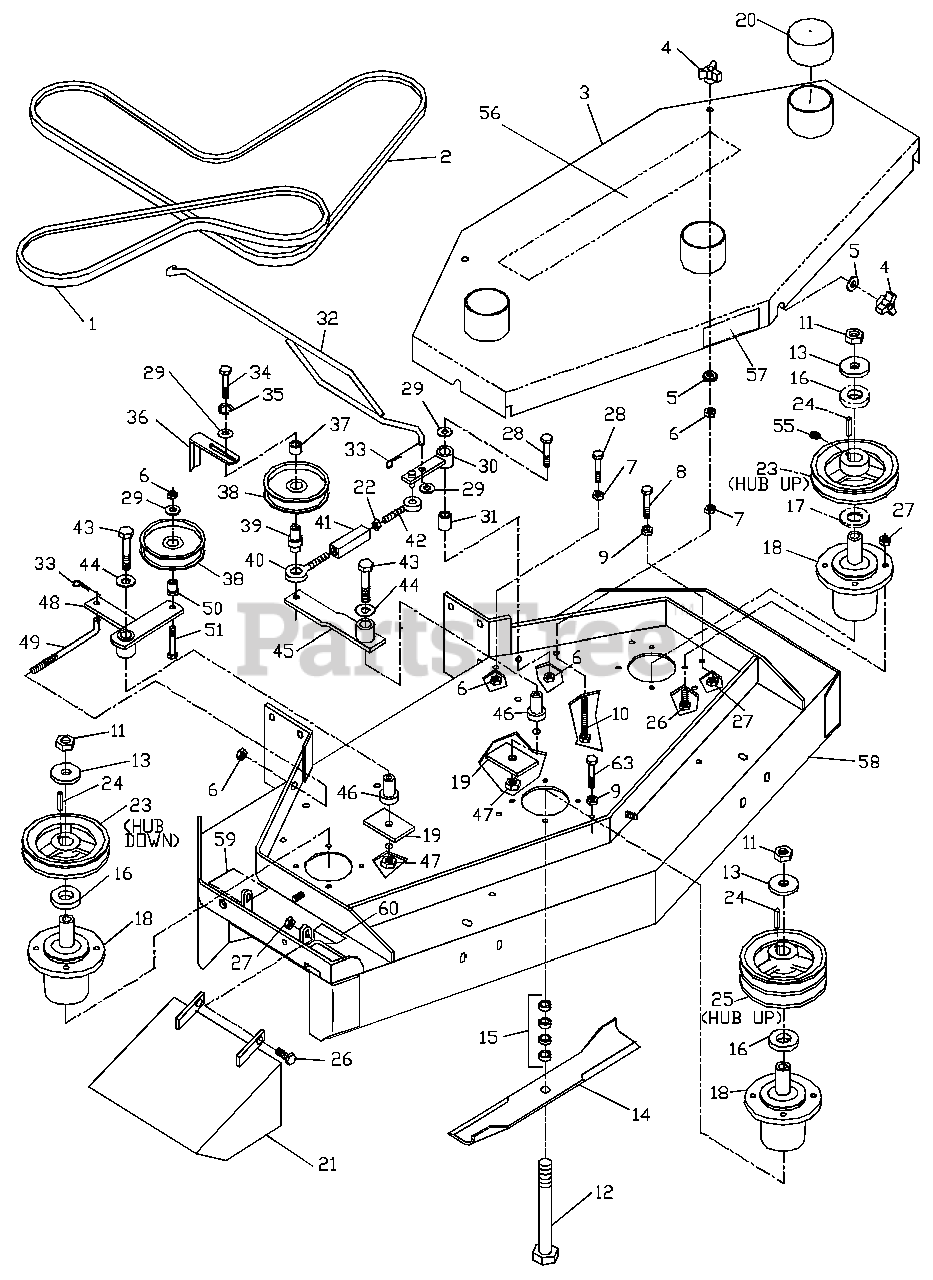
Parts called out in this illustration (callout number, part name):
1	AUX. BLADE BELT
2	BLADE BELT 48
3	48" BELT SHIELD
4	THREE PRONG KNOB
5	3/8 SEALING WASHER
8	HCS 5/16CX3 (BELT GUIDE)
9	HFLN 5/16C
10	TAPBOLT-3/8C X 4 1/2
12	HCS 5/8F X 8 1/2
12	HCS 5/8F X 9 (CENTER)
13	SUPPORT WASHER
14	BLADE 16 1/4"
15	BLADE SPACERS
17	MACH. BUSHING 10 GA.
18	HOUSING ASM.
21	DEFLECTOR CHUTE
22	5/16C HEX NUT
23	PULLEY W/SETSCREWS
24	1/4SQ. KEY X 1 1/8
25	DOUBLE PULLEY W/SETS.
26	HCS 5/16C X 1
28	HCS 3/8C X 2 1/4
29	FW 3/8 STD
30	ENGAGEMENT ARM
31	SLEEVE BUSHING
32	LOWER LINK
33	#2 HAIRPIN
34	HCS 3/8C X 2 1/2
35	3/8 LOCK WASHER
38	IDLER PULLEY
39	EYEBOLT PIVOT
40	LEFT HAND EYEBOLT
41	TURNBUCKLE
42	RH. EYEBOLT
43	HCS 1/2C X 2 3/4
44	1/2 FLAT WASHER
46	IDLER SPINDLE
47	1/2C NYLOC NUT
48	AUX. IDLER ARM
49	TENSION ROD
50	IDLER FLANGE BUSHING
51	HCS 3/8C X 1 3/4
55	5/16 NYLOC SETSCREW
56	DECAL, HUSQVARNA
57	DECAL, NASCAR
58	48" DECK W/DECALS
59	DECAL, DANGER
60	DECAL, CPSC
63	HCS 5/16C X 4
